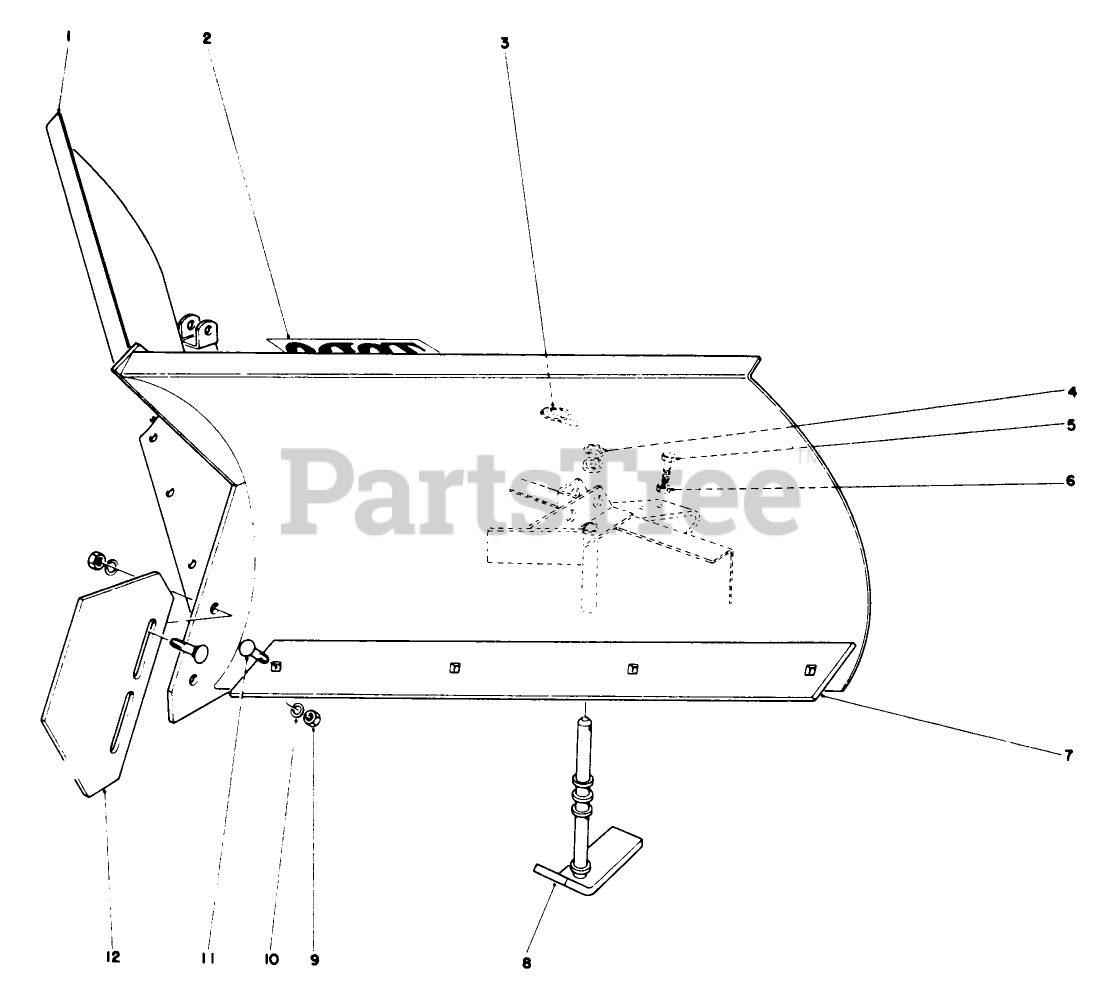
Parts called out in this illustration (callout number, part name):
1	V-Plow
2	Decal
3	PIN-LYNCH
4	SPACER TUBE B
5	SCREW-HH
6	NUT-JAM
7	Blade-Scraper
8	Skid
9	NUT-HH
10	WASHER-LOCK
11	SCREW-CARR
12	Nose Skid
